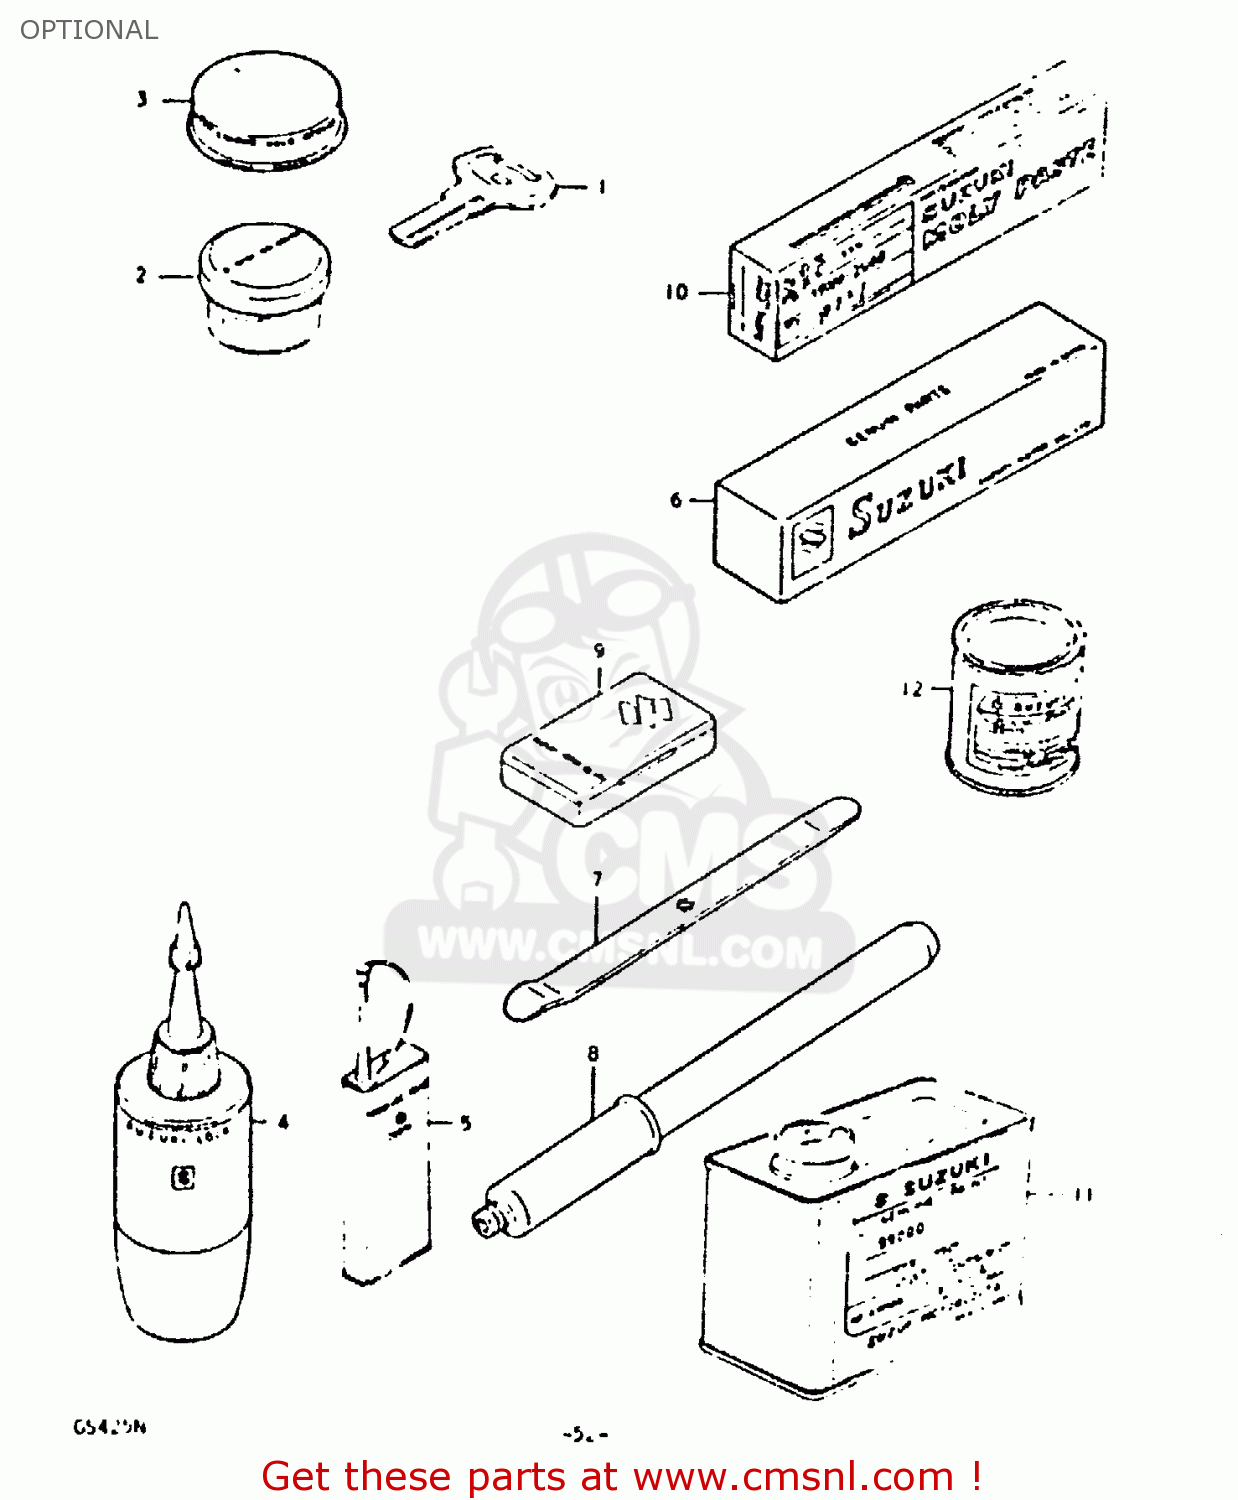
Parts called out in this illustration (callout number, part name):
1	KEY,BLANK
2	GREASE,PBC FOR BRK PAD 20G
3	GREASE,SILICON 20G
4	THREAD LOCK NO.1303B PURPL 50G
5	THREAD LOCK NO.1401 CLEAR 200G
6	BOND 1104
7	LEVER,TIRE
8	INFLATOR, AIR
9	TUBE REPARING TOOL
10	SUZUKI MOLY PASTE
11	PAINT (BLACK)
12	PAINT,BLACK
13	GASKET SET
